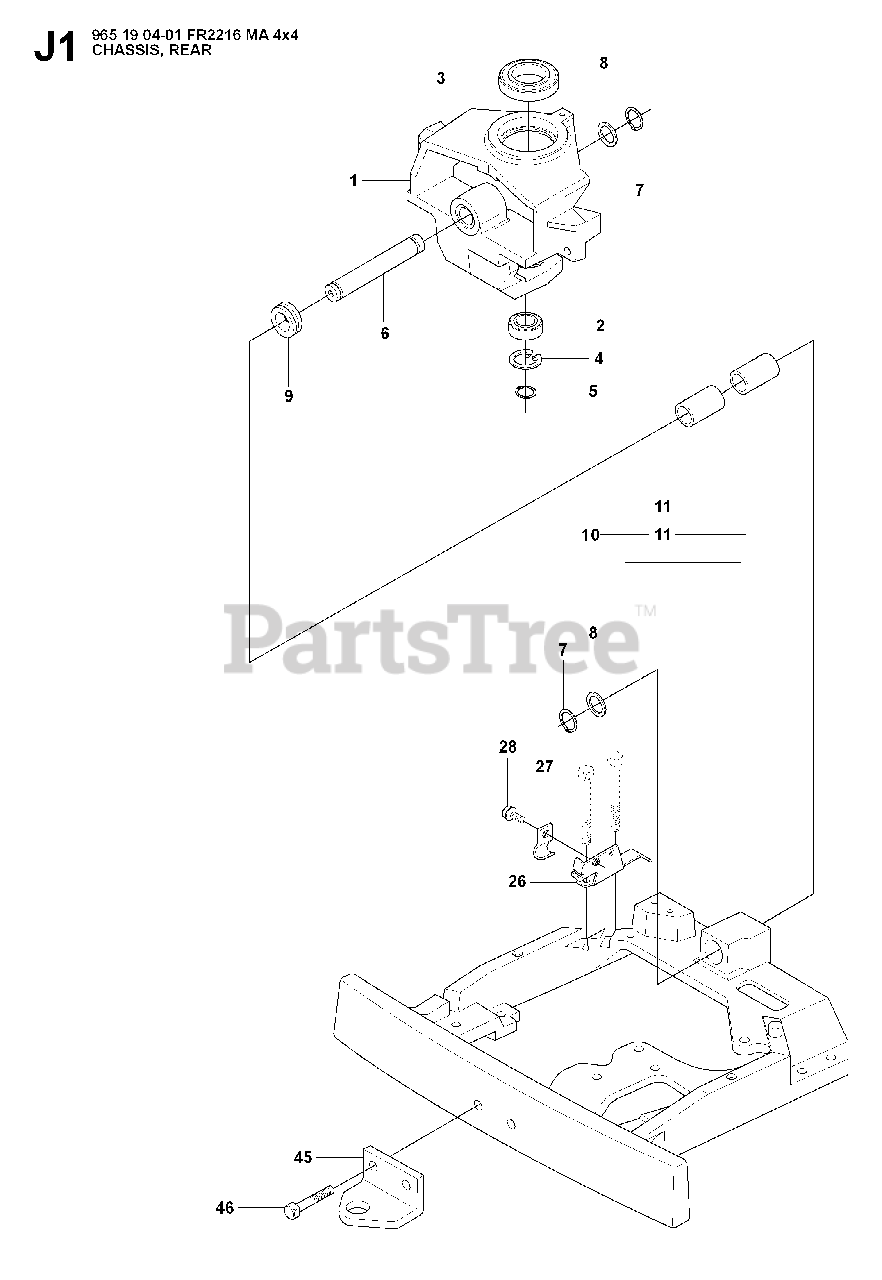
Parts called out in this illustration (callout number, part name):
2	BALL BEARING 6005-2RS
3	BALL BEARING 6010 2RS1
4	CIRCLIP SGH 47
5	RETAINING RING SGA 25
7	RETAINING RING SGA 25
45	DRAW RING
46	SCREW M10X25
